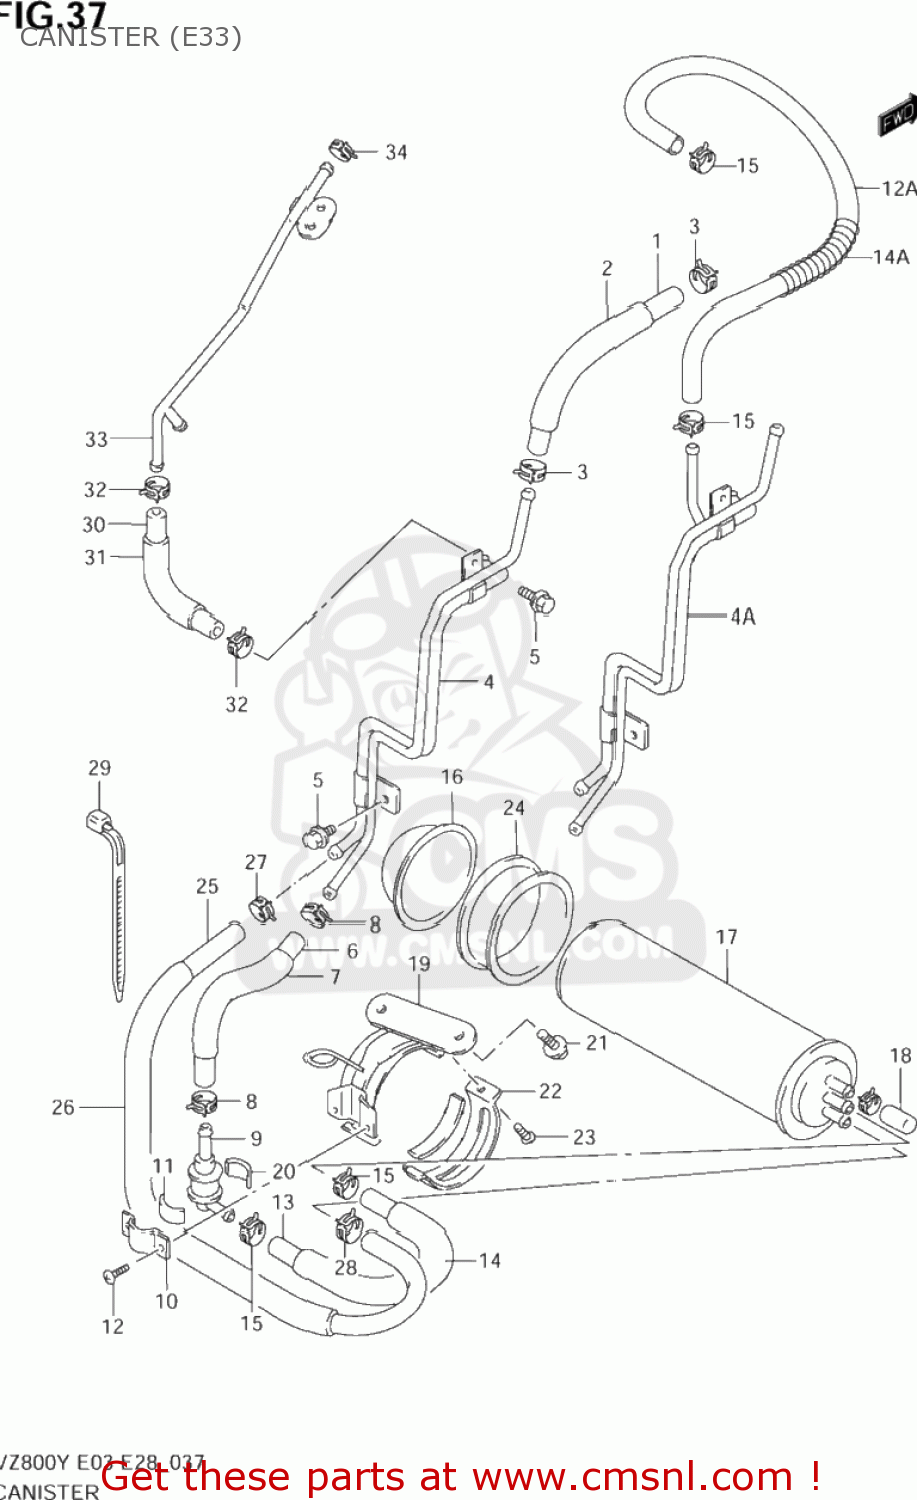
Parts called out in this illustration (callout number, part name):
1	HOSE TANK & BREATHER VALVE
2	SPRING
3	CLIP
4	PIPE COMP,TANK & BREATHER
4A	PIPE,TANK & BREATHER
5	BOLT
6	HOSE(5.4X11.4X600)
7	SPRING
8	CLIP
9	VALVE,FUEL TANK BREATHER
10	PLATE,FUEL TANK BREATHER NO.2
11	CUSHION
12	SCREW
12A	HOSE(5.4X11.4X2000)
13	HOSE,CSTR & BREATHER VALVE
14	SPRING
14A	(CA) SPRING
15	CLIP
16	CAP,CANISTER
17	CANISTER ASSY,CHARCOAL
18	CAP,OD:11.5
19	BRACKET,CANISTER
20	CUSHION
21	BOLT
22	HOLDER,CANISTER
23	SCREW 6X10
24	CUSHION,CANISTER
25	HOSE,CSTR & CARB
26	SPRING
27	CLIP
28	CLIP
29	CLAMP(L:125)
30	HOSE(5.4X11.4X600)
31	SPRING
32	CLIP
33	PIPE,CSTR & CARB
34	CLIP
